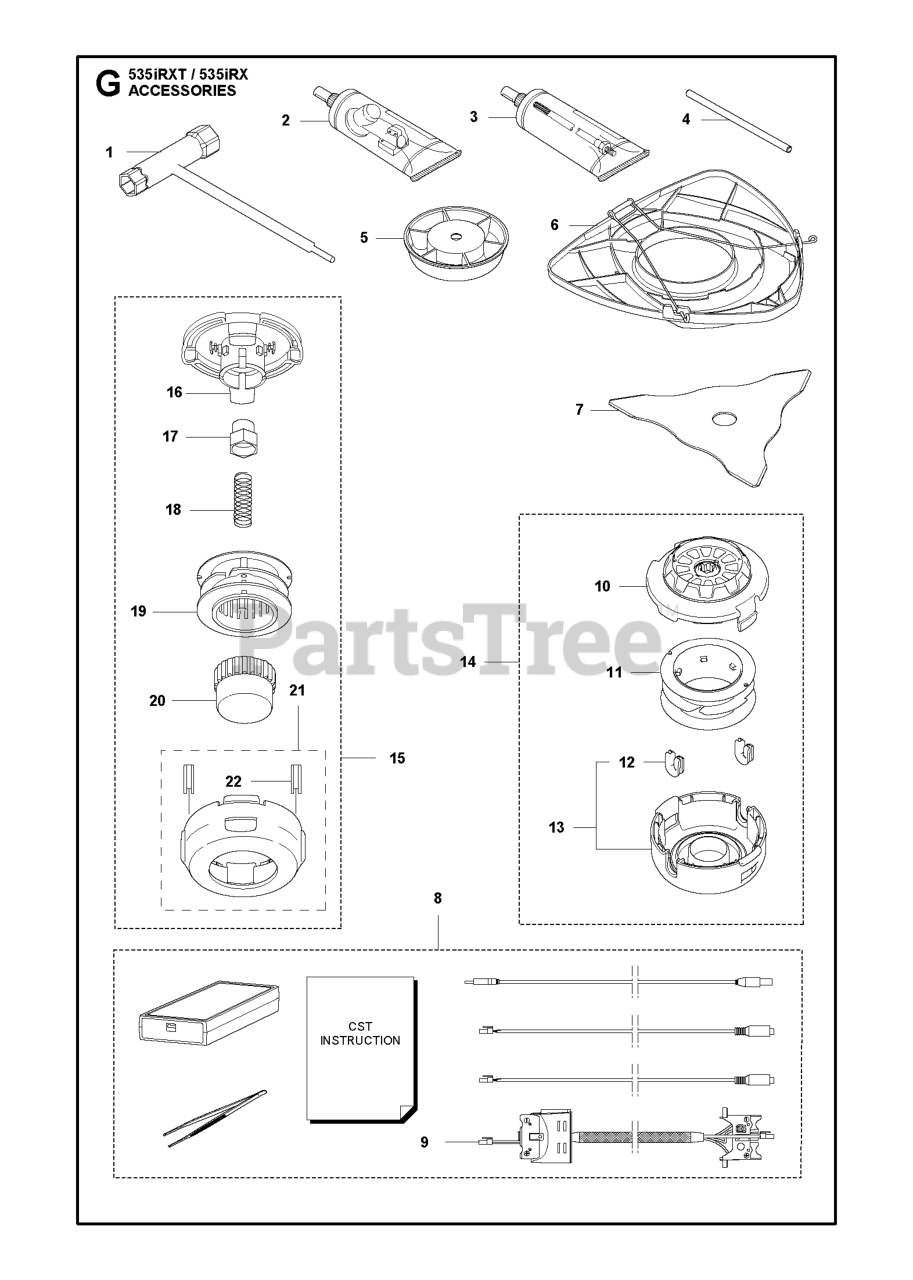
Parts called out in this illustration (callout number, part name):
1	COMBINATION WRENCH TORX
2	BEVEL GEAR GREASE
3	DRIVE SHAFT GREASE (200 G)
4	LOCKING PIN
5	SUPPORT CUP
6	TRANSPORT GUARD
8	DIAGNOSTIC TOOL KIT
9	WIRING ASSY
15	TRIMMER HEAD T35 M12L
21	TRIMMER HEAD HOUSING
